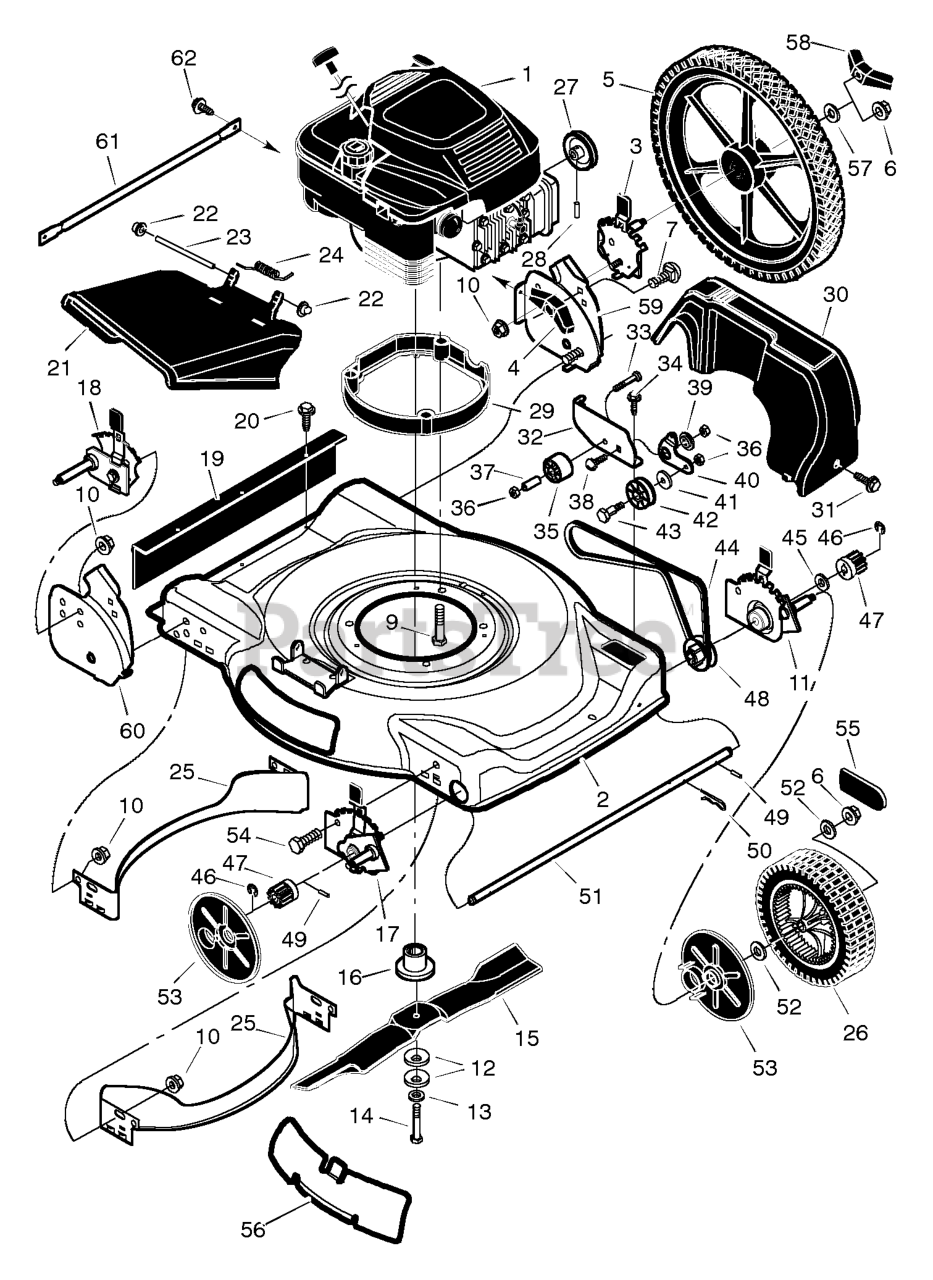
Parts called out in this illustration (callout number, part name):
1	Engine *
2	Housing
3	Height Adjuster, Left Rear
5	Wheel and Tire, Rear
6	Locknut, Flange
7	Bolt, Carriage
9	Bolt, Engine
10	Nut
11	Height Adjuster, Left Front
12	Washer, Belleville
14	Bolt, Hex
16	Adapter, Blade
17	Height Adjuster, Right Front
18	Height Adjuster, Right Rear
19	Guard, Rear
21	Deflector, Chute
22	Push- On Cap
23	Pin, Pivot
26	Wheel and Tire, Drive
28	Pin, Spring
29	Base, Engine
30	Cover, Belt
32	Bracket, Idler Support
36	Locknut
37	Bearing
38	Bolt, Carriage
40	Arm, Idler
42	Pulley, Idler
43	Bolt, Shoulder
46	Ring, Retainer
47	Gear, Pinion
49	Pin, Drive
50	Pin, Hair
52	Washer
53	Cover, Dust
54	Bolt
55	Hub Cap
56	Plate, Mulch
58	Knob, Axle
59	Bracket, Left Handle
60	Bracket, Right Handle
